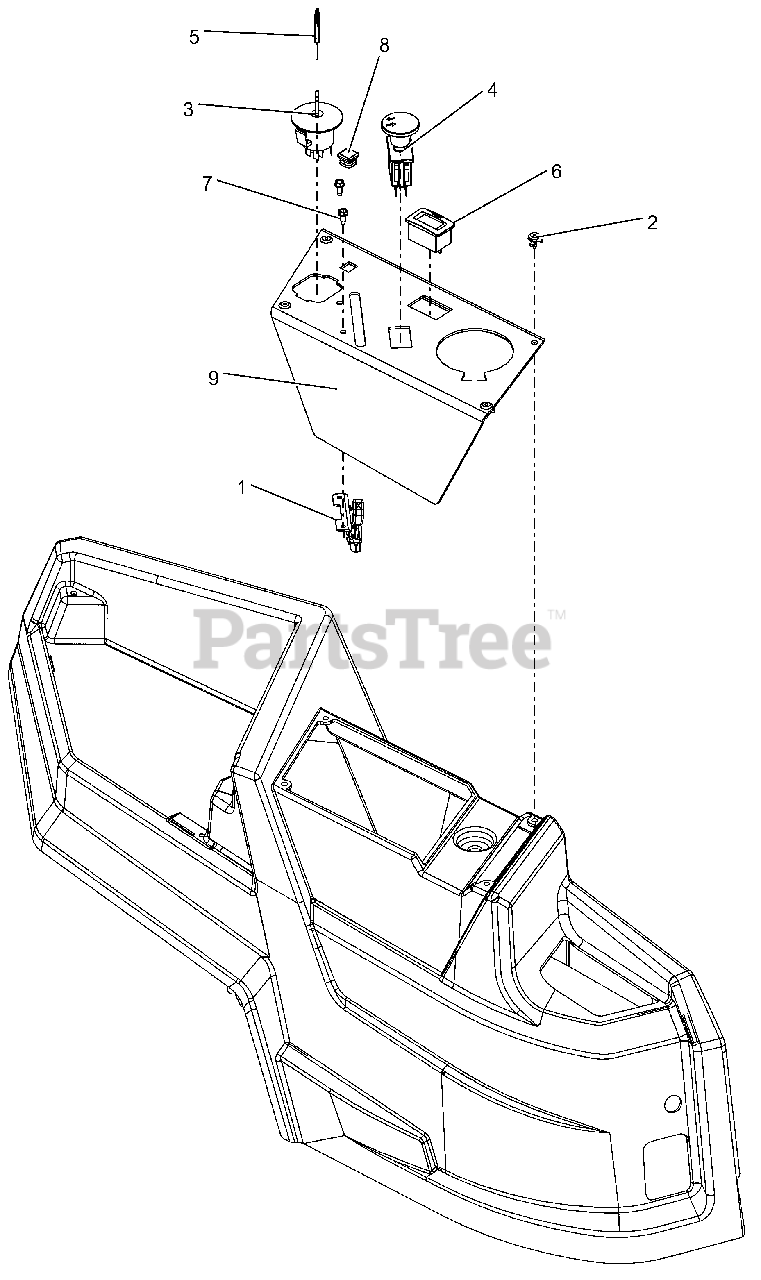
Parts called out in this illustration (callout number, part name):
1	CABLE - THROTTLE CONTROL
2	RIVET, PLASTIC .195 DIA.
3	KEYSWITCH-IGNITION 4 POS
4	SWITCH, CLUTCH (YELLOW)
5	KEY, IGNITION
6	HOUR METER
7	SCR,TAP #10-24X.50 HWH TR ZCC
8	PLUG, 5/8" SQ BLACK (14-20GA)
9	PANEL, CONTROL
